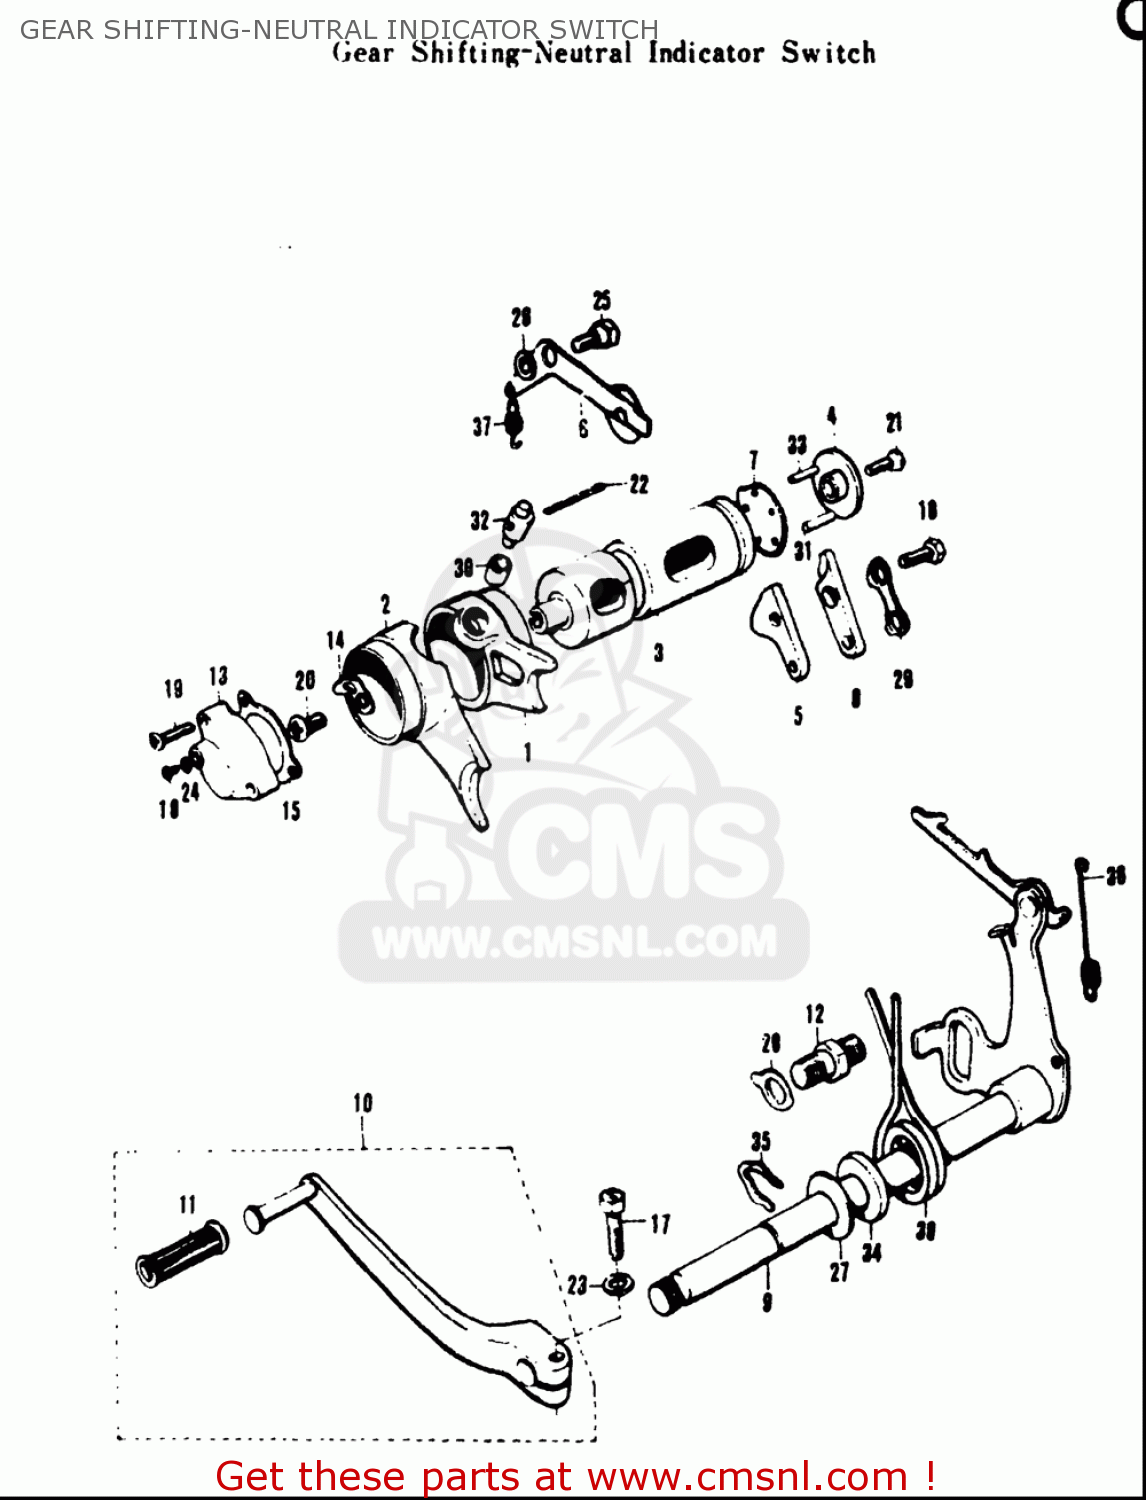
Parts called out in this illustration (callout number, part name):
4	RETAINER,GEAR SHIFT CAM DR PIN
7	SHIFTING CAM SIDE PLATE
11	RUBBER,GEAR SHIFT PEDAL
13	BODY,CHANGE SWITCH
14	CONTACT,GEAR SHIFT SWITCH
15	GASKET,GEAR SHIFT SWITCH (NAS)
16	BOLT
17	BOLT
19	SCREW 4X16
22	PIN
23	WASHER,LOCK
24	WASHER
25	BOLT(6X16.1)
26	WASHER (6.5X13X1)
27	WASHER (12.5X26X1.6)
29	WASHER
30	SPACER(6X9.8X6)
31	PIN
33	PIN(4X20)
34	SEAL,OIL (12X22X9)
35	CIRCLIP,12 MM
36	SPRING
